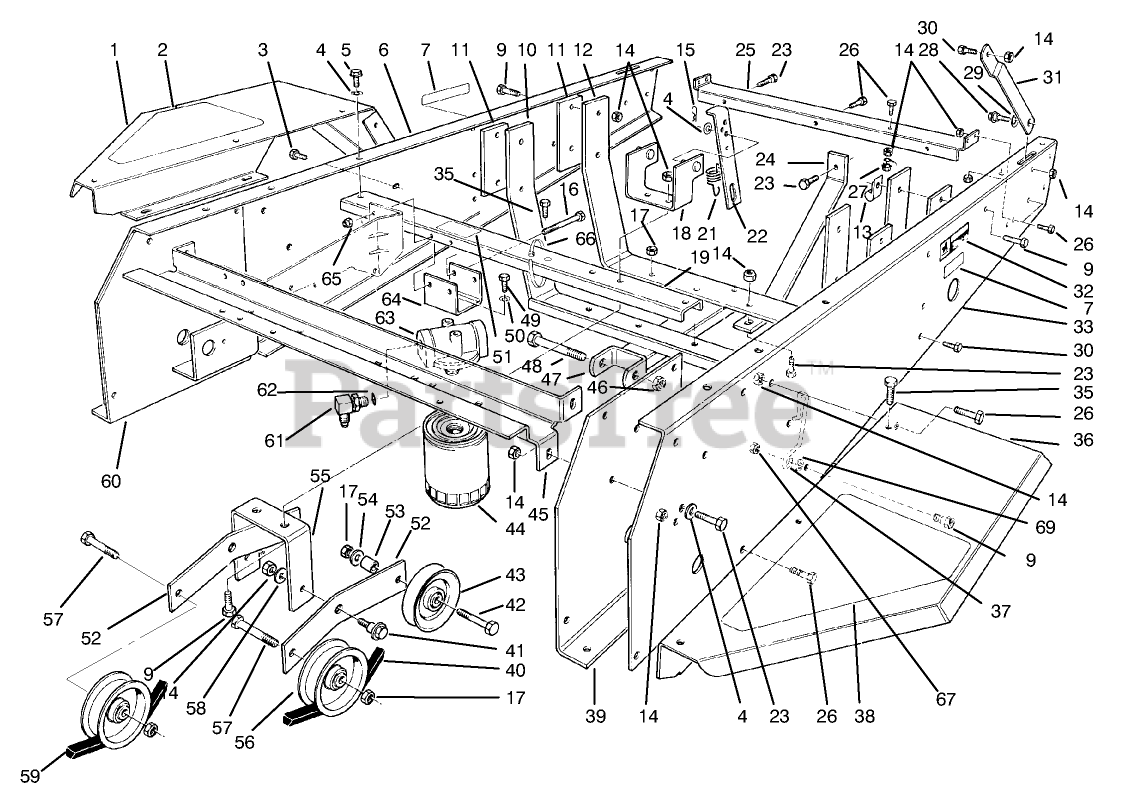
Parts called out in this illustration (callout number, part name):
1	Fender R.H
2	RH FENDER PAD
3	SCREW-HHF
4	WASHER-PLAIN
5	SCREW-HWHTF
6	Channel-Side R.H.
7	DECAL-WARNING
9	SCREW-HH
10	Mount-Engine
11	REAR ENG PLATE
12	Mount-Engine
14	NUT-LOCK, NI
15	PIN-COTTER
16	SCREW-HH
17	NUT-LOCK, NI
18	Anchor-Spring
19	MIDDLE CHANNEL WA B
20	SCREW-HH
21	IDLER SPRING
22	IDLER ANCHOR LINK
23	SCREW-HH
24	Bar-Tension
25	Support-Shield
26	SCREW-HH
27	NUT-KEPS
28	SCREW-SHOULDER
29	WASHER-SPRING
30	SCREW-HH
31	Stop-Hood Lower
32	DECAL-SURFACE, HOT
33	Channel-Side LH.
35	SCREW-HHFTF
36	Fender L.H.
37	BELT GUIDE
38	LH FENDER PAD
39	Axle Stand-LH.
40	V-BELT, JACKSHAFT
41	SCREW-SHOULDER
42	SCREW-HH
43	PULLEY
44	FILTER-OIL, TRANSMISSION
45	Channel-Front
46	NUT-LOCK
47	Mount-Cylinder
48	SCREW-HH
49	SCREW-HH
50	WASHER-LOCK
51	DECAL-OIL
52	IDLER LEVER
53	SPACER-WEIGHT
54	WASHER-FLAT
55	IDLER MT BRKT
56	PULLEY
57	SCREW-HH
58	WASHER
59	V-BELT, TRACTION
60	Axle Stand R.H.
61	FITTING-ELBOW, 90
62	O-RING
63	FILTER HD ASM
64	BRACKET - FILTER HEAD
65	NUT-LOCK, NI
66	TIE-CABLE
67	NUT-HF
69	WASHER-LOCK
